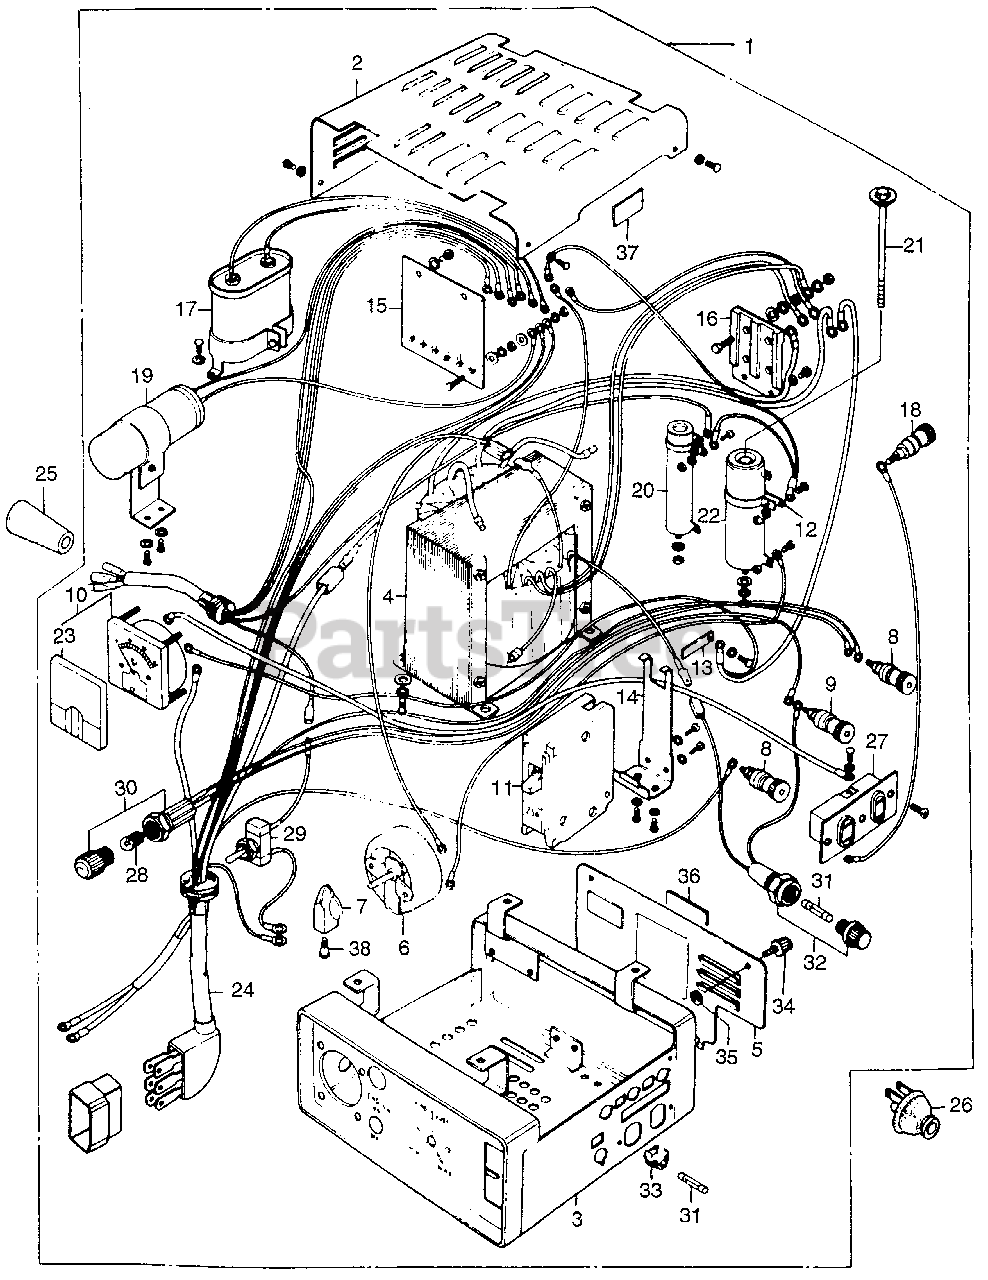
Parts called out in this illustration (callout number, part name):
1	BOX ASSY., CONTROL *R8* (BRIGHT RED)
2	COVER, CONTROL BOX (UPPER) *R2* (SCARLET)
3	COVER, CONTROL BOX (LOWER)
4	TRANSFORMER ASSY., CURRENT
5	PANEL, RR. CONTROL BOX
6	RESISTOR ASSY., VARIABLE (NOT AVAILABLE)
7	KNOB, ADJUSTING
8	TERMINAL, D.C. OUT (+)
9	TERMINAL, D.C. OUT (-)
10	VOLTMETER ASSY. (150V SCALE)
10	VOLTMETER ASSY.
11	BREAKER, CIRCUIT (21A)
12	PLATE, RESISTOR
13	TERMINAL, BREAKER
14	SUPPORT, BREAKER (NOT AVAILABLE)
15	STACK ASSY., DIODE
16	STACK ASSY., FREQUENCY CHANGE
17	CONDENSER ASSY.
18	TERMINAL ASSY., GROUND (NOT AVAILABLE)
19	CONDENSER ASSY.
20	RESISTOR, ADJUSTABLE
21	BOLT, RESISTOR SET
22	RESISTOR SET
23	LENS, METER (NOT AVAILABLE)
24	WIRE HARNESS (6P)
25	CONNECTOR ASSY. (OUTER) (4P)
26	PLUG ASSY., RECEPTACLE
27	RECEPTACLE (15A-125V)
28	BULB (24V2W)
29	SWITCH ASSY., ENGINE (NOT AVAILABLE)
30	SOCKET ASSY., PILOT LAMP
32	HOLDER ASSY., FUSE
33	SUPPORTER, SPARE FUSE
34	LATCH, SIDE PLATE
35	STOPPER, LATCH (NOT AVAILABLE)
36	PLATE, DESCRIPTION
37	MARK C, CAUTION
38	BOLT, ADJUSTABLE RESISTOR (NOT AVAILABLE)
38	BOLT, KNOB (NOT AVAILABLE)
